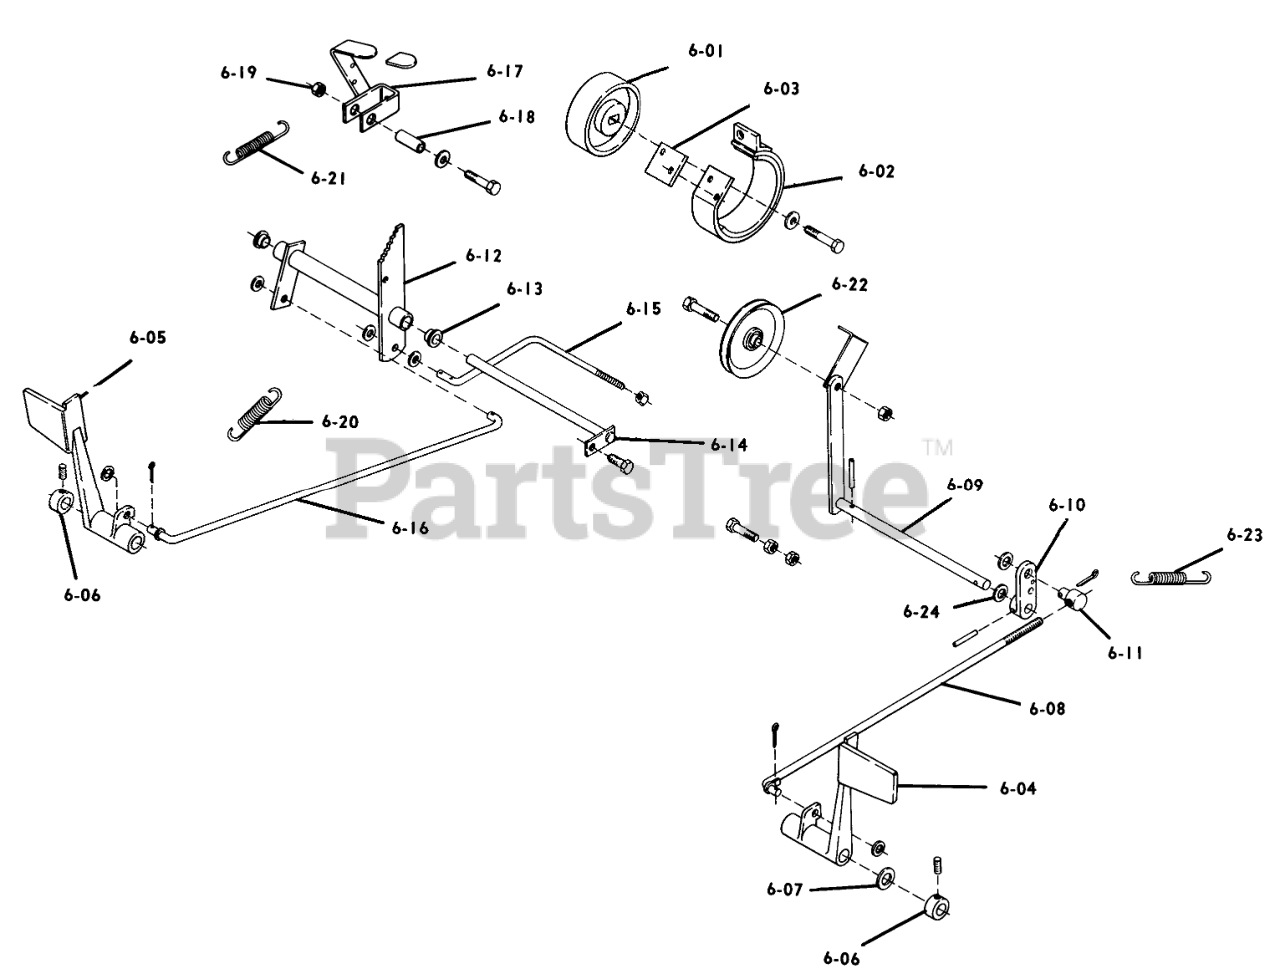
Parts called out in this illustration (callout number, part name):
6-01	Brake Drum
6-02	BRAKE BAND ASM
6-03	Plate-Stop
6-04	Clutch Pedal
6-05	PEDAL-BRAKE R
6-06	Collar
6-07	WASHER-BOWED
6-08	ROD AND GUIDE ASM
6-09	Idler Arm Assembly
6-10	Clutch Pivot Arm
6-12	Bellcrank Assy
6-13	BUSHING-FLANGED
6-14	Rod Assy
6-15	Brake Rod
6-16	Rod
6-17	Brake Lever Assy
6-18	SPACER
6-19	LOCKNUT-FLANGE
6-20	Spring
6-21	SPRING-EXTENSION
6-22	PULLEY-IDLER
6-23	Spring
6-24	SHIM-WASHER
